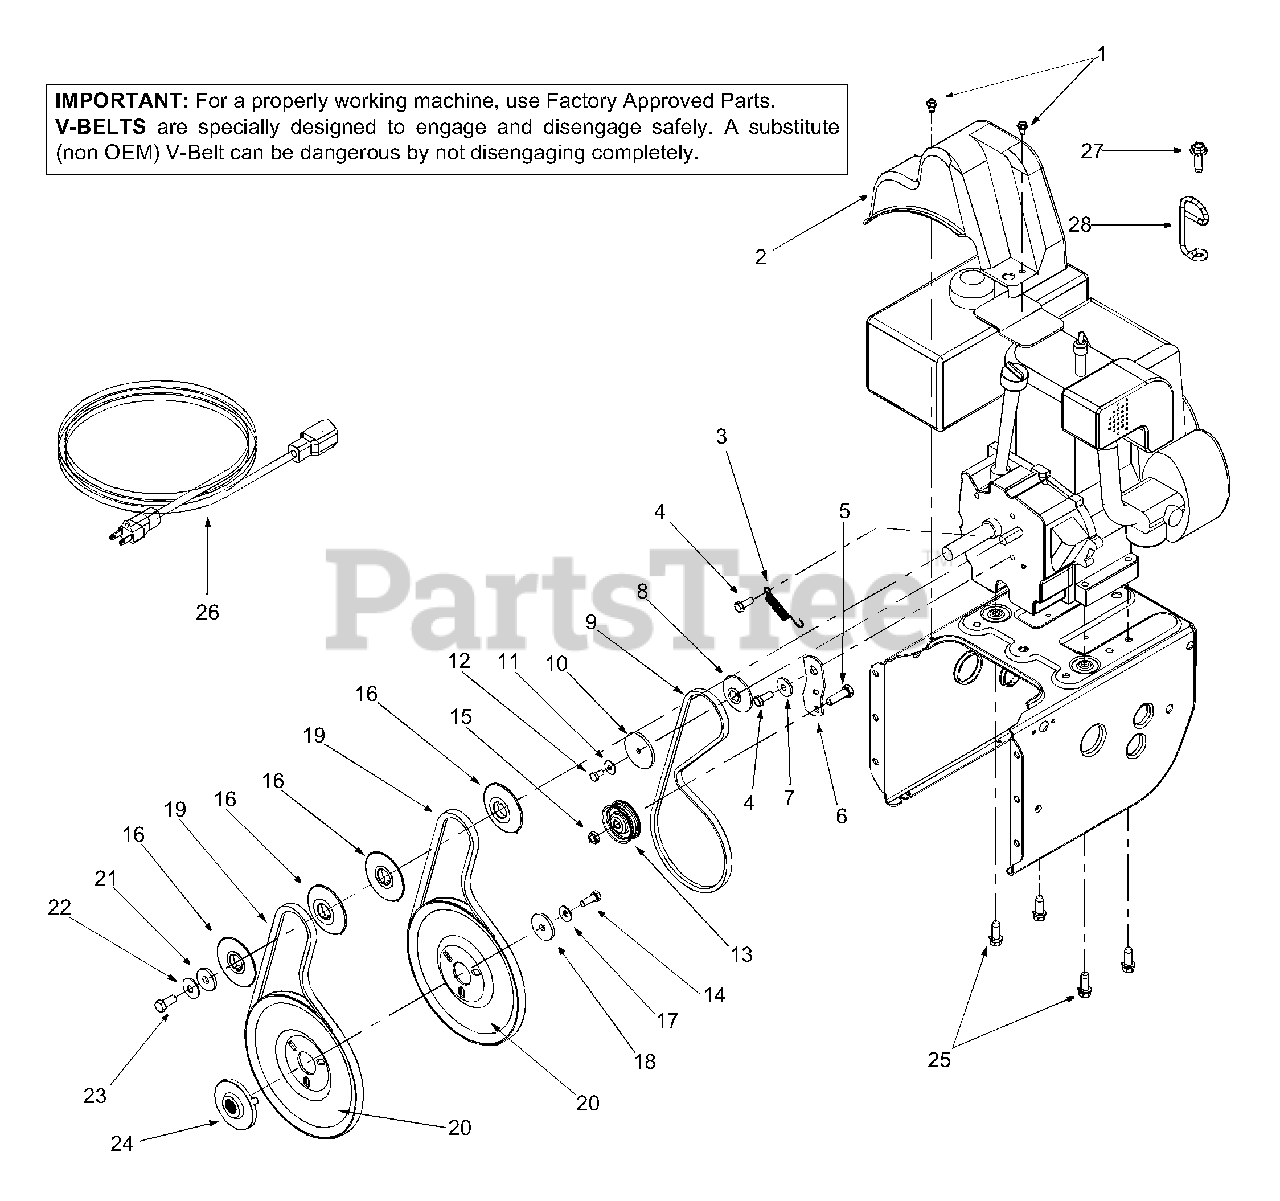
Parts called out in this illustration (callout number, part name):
1	Hex Washer Screw 1/4-20 x.625
2	Belt Cover
3	Extension Spring
4	Hex Screw 5/16-24 x.75
5	Hex Cap Screw 3/8-16 x 1.25
8	Pulley Half
9	V-Belt
10	Pulley Half
11	Bell Washer
12	Hex Cap Screw 1/4-28 x.50
13	Flat Idler
14	Lock Hex Cap Screw 5/16-24
15	Lock Jam Nut 3/8-16
16	Pulley Half
17	Bell Washer
18	Flat Washer
19	Belt
20	Auger Pulley
21	Flat Washer 3/8 x 1.25 OD
22	Bell Washer
23	Hex Cap Screw 3/8-24
24	Pulley Adapter
25	Hex Screw 3/8-16 x 1.0
26	Extension Cord, Three-Prong
27	Self Tapping Screw 5/16-18
28	Cable Guide
